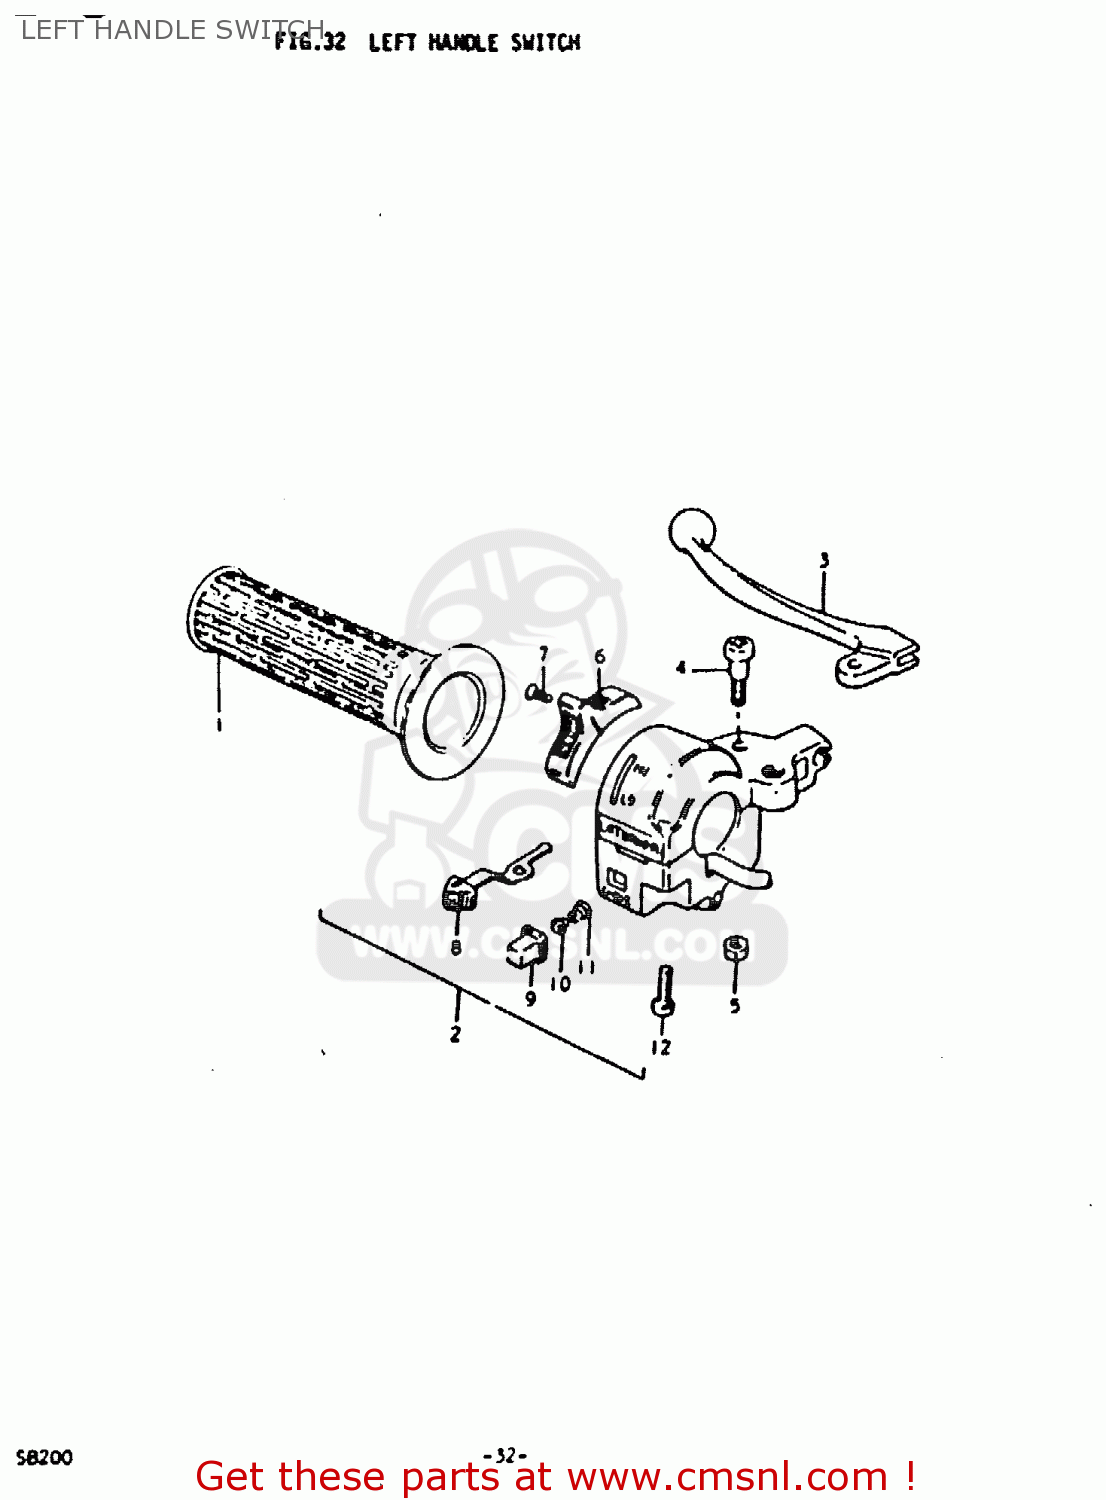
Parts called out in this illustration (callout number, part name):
1	GRIP,L
2	LEVER ASSY, CLUTCH
3	LEVER, CLUTCH
4	BOLT,LEVER
5	NUT,LEVER BOLT
6	KNOB
7	SCREW 3X6
8	KNOB, TURN SIGNAL
9	BUTTON,HORN
10	CONTACT
11	SPRING
12	SCREW 5X20
